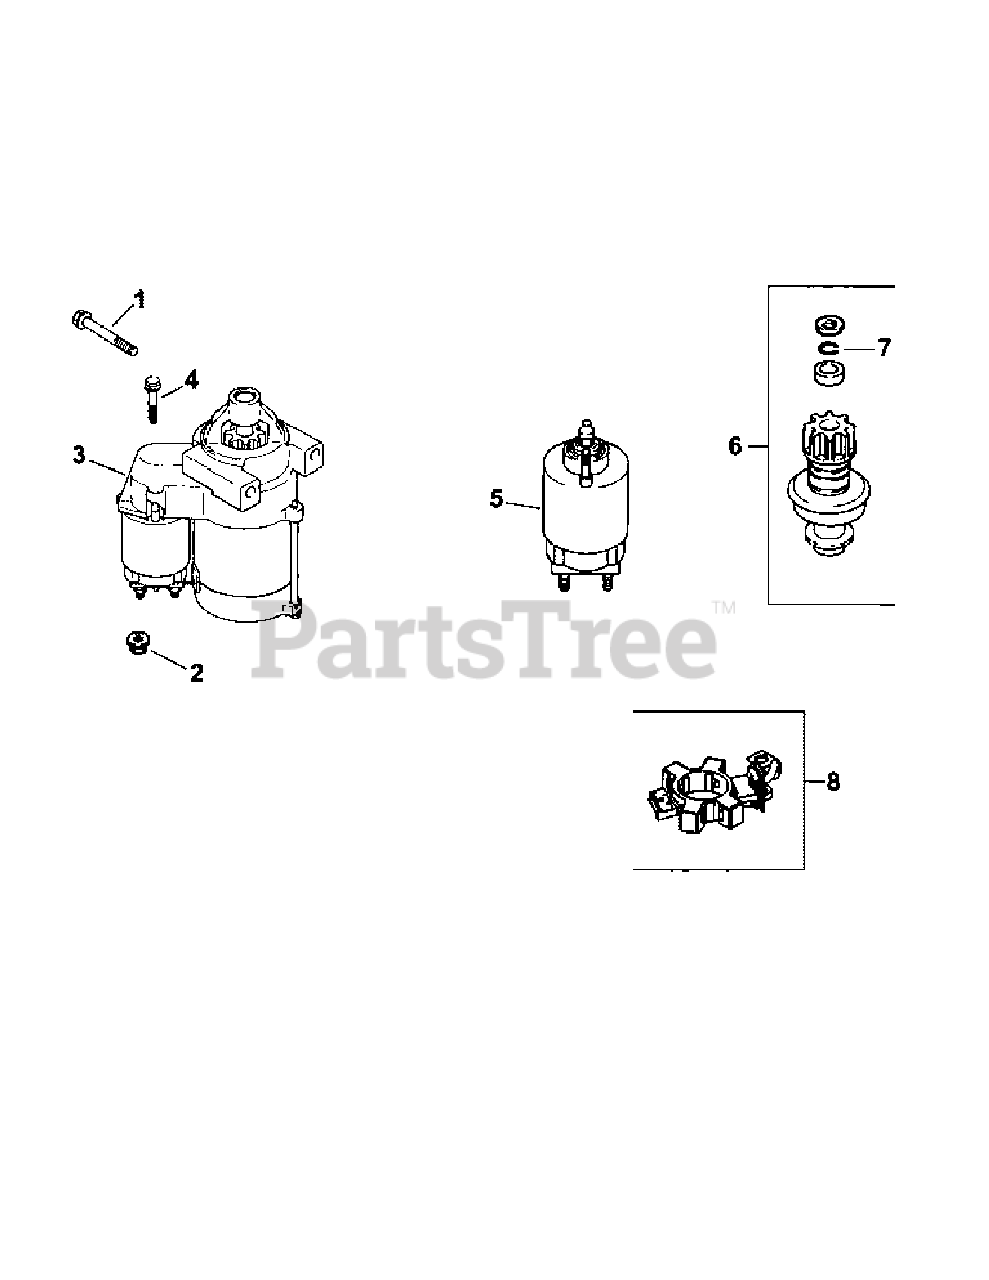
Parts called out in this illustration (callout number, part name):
1	Hex Flange Screw (M8 x 1.25 x 80)
2	Hex Flange Nut (M8 x 1.25)
3	Solenoid Shift Starter
4	External Torx Head Screw
6	Starter Pinion Kit
